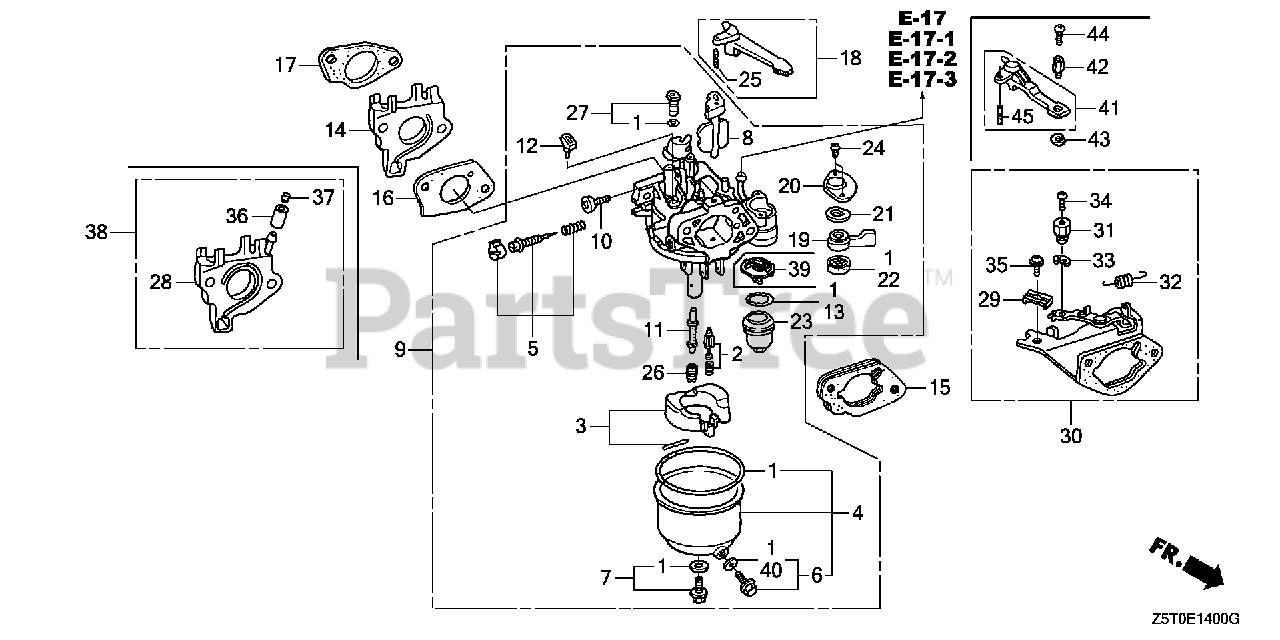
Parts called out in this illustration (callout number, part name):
1	GASKET SET (INCLUDES 16173-001-004)
2	VALVE SET, FLOAT
4	CHAMBER SET, FLOAT
5	SCREW SET, PILOT
6	SCREW SET, DRAIN
9	CARBURETOR ASSY. (BE94F A)
10	SCREW, THROTTLE STOP
11	NOZZLE, MAIN
12	COLLAR, SETTING
13	GASKET, FUEL STRAINER CUP
14	INSULATOR, CARBURETOR
15	SPACER, CARBURETOR
16	GASKET, CARBURETOR
17	GASKET, CARBURETOR INSULATOR
18	LEVER, CHOKE (STD)
19	LEVER, PETCOCK
20	PLATE, LEVER SETTING
21	SPRING, PETCOCK LEVER
22	GASKET, PETCOCK
23	CUP, FUEL STRAINER
24	SCREW, PAN (3X6)
25	PIN, SPRING (2X12)
26	JET, MAIN (#100)
26	JET, MAIN (#105)
26	JET, MAIN (#108)
27	JET SET, PILOT (#45)
39	FILTER, CUP
40	WASHER, PLAIN (6.2X10.7 DRAIN)
